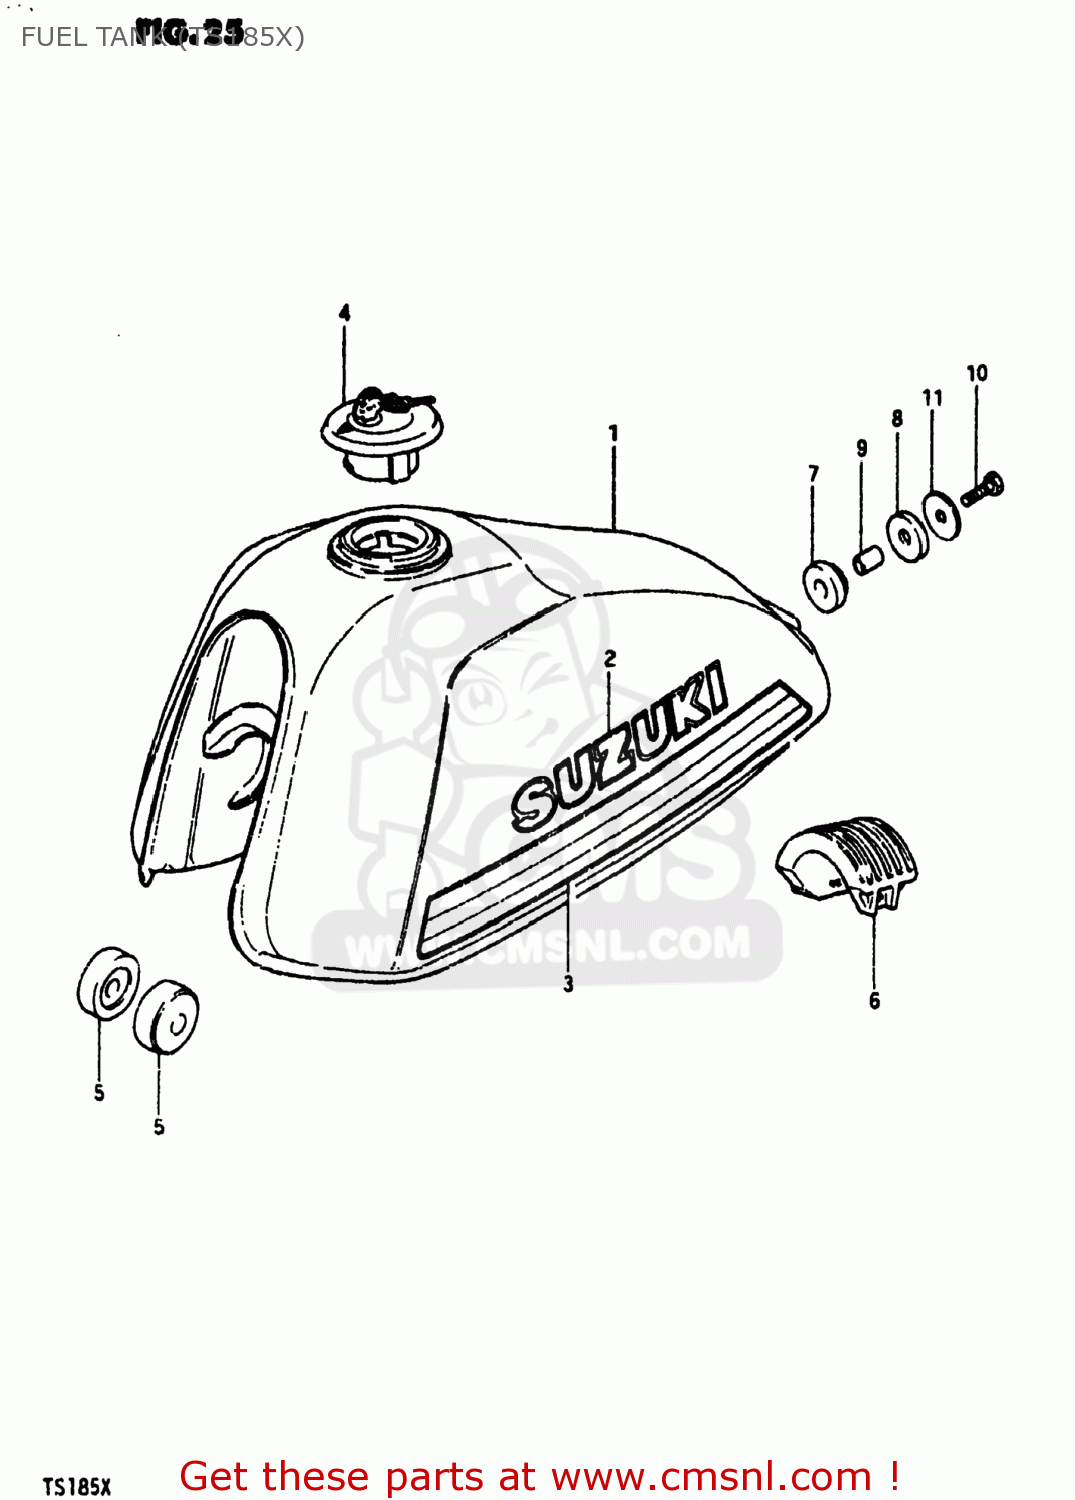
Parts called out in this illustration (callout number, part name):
1	TANK ASSEMBLY,FUEL
2	EMBLEM,FUEL TANK
3	TAPE SET,FUEL TANK
4	CAP SET,FUEL TANK
5	CUSHION
6	CUSHION,FUEL TANK
7	CUSHION
8	CUSHION
9	SPACER(8.5X12X19)
10	BOLT (8X30)
11	WASHER (8.5X29X1.6)
